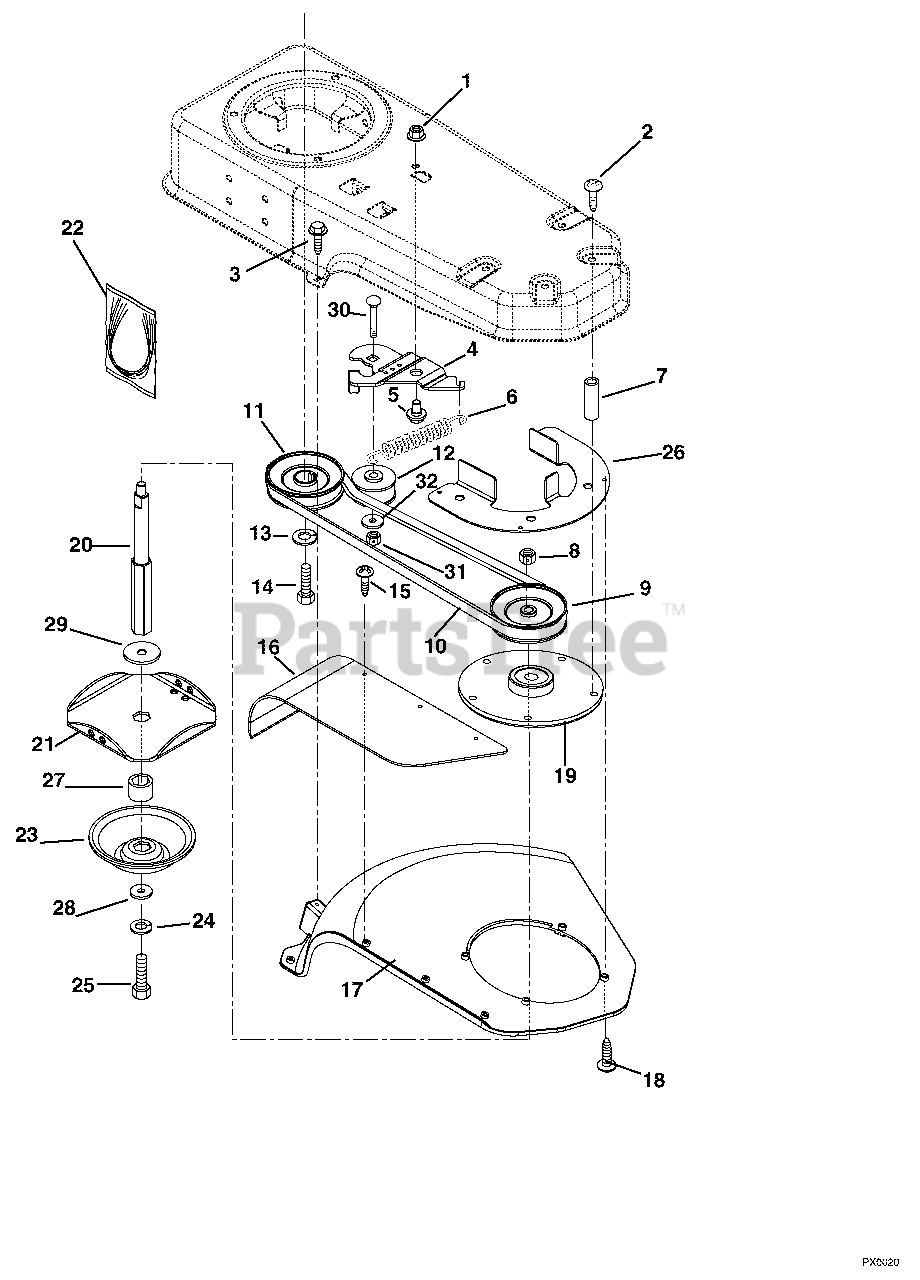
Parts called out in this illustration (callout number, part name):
1	NUT-LK-CTR-FLG .38-16 YWZC
2	@SCR-TAP.375-16X2.75 HWH TR YZ
3	SCR-TAP 10-24X.75 HWH TR YWZC
4	BRACKET - IDLER
5	BOLT-SHLDR .375-16X.150
6	SG-TENS .035X.45X2.75 WLD 3.5
7	BSHG-SPCR .406X.625X1.90
8	NUT-LK-FLG .375-24 GR5 YWZC
9	PLY-V 3.50 OD X .87 WIDE (CUT)
10	V-BELT, HA-RAW EDGE
11	SHEAVE-ENGINE 3.50 ODX.87 WIDE
12	IDLER - FLAT 1.875OD X .75WIDE
13	@WSHR-LK .38X.094 REG YWZC
14	BLT-HEX .38-24X1.0 YWZC GR5
15	SCR-TAP #10-16 X .625 HWH
16	GUARD - DEBRIS
17	SHIELD - TRIMMER
18	SCR-TAP 10-24X.75 HWH TR YWZC
19	HOUSING - JACKSHAFT
20	SHAFT - CUTTER - HEX
21	DISC - CUTTER - HEX
22	LINE - CUTTER 18" LG PKG OF 6
23	GUIDE - HEIGHT - HEX
24	@WSHR-LK .31X.078 REG YWZC
25	@BLT-HEX .31-18X.75 GR5 YWZC
26	FINGER - BELT
27	SPACER - HEX
28	WSHR-FL-STL .344X1.125X.135
29	SHIELD - DUST
30	@BLT-RHDSSQNK .38-16X1.50 G5YZ
31	@NUT-LK-CTR .38-16 YWZC
32	@WSHR-FL-STL.406X.812X.065 YWZ
